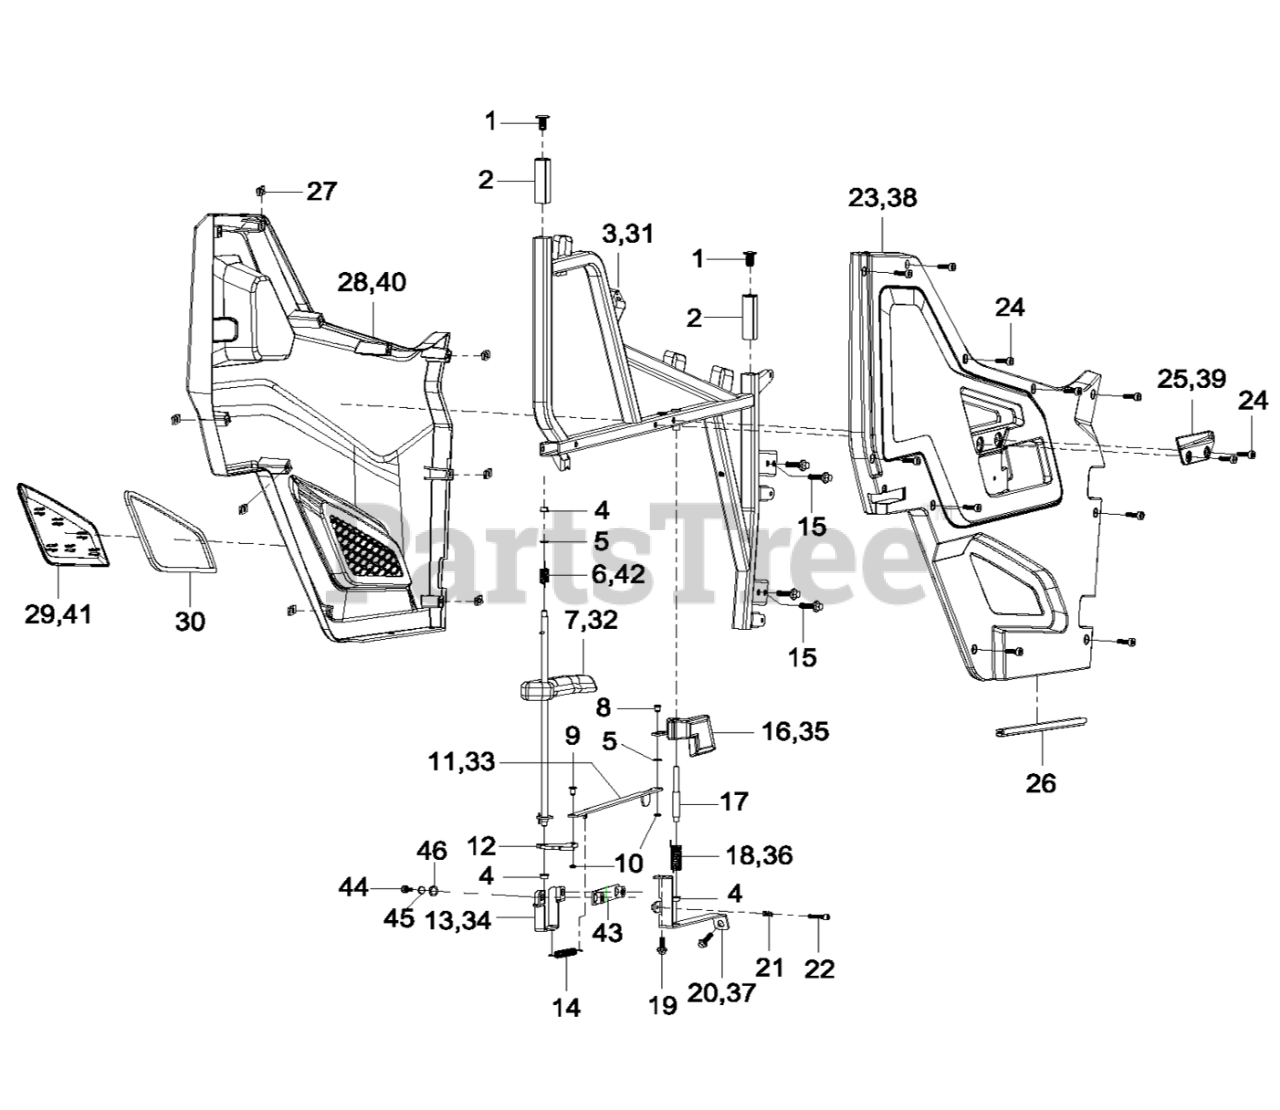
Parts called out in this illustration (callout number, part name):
1	PLUG - DOOR
2	UPPER DOOR SEAL
3	DOOR FRAME - LEFT LOWER
4	BUSHING PLASTIC 8X11
6	RETURN SPRING
7	OUTSIDE DOOR HANDLE KIT - LEFT
8	PIN - SHOULDER 8X11
9	PIN - SHOULDER 8X14
11	DOOR LOCK ROD - LEFT
12	DOOR LOCK KIT
13	INSIDE DOOR LOCK LEVER - LEFT
14	EXTENTION SPRING
15	HEXAGON FLANGE BOLT M8X20
16	INSIDE DOOR HANDLE KIT - LEFT
17	PIN - SHOULDER 8X104-12X47
18	SPRING - TORSION
19	HEXAGON FLANGE BOLT M6X16
20	INSIDE DOOR LOCK LEVER - LEFT
21	EXTENTION SPRING
22	HEX HEAD CAP SCREW M6X40
23	DOOR PROTECTOR - LEFT INSIDE I
24	SOCKET HEX FLAT HEAD BOLT M6X16
25	DOOR PULL - LEFT
27	CLAMP NUT M6X6
28	DOOR PROTECTOR - LEFT OUTSIDE I
29	DOOR BREATHER COVER - LEFT (RED)
29	COVER DOOR BREATHER (LH) (YELLOW)
29	COVER DOOR BREATHER LH BLUE
29	COVER DOOR BREATHER LH BLACK
29	COVER DOOR BREATHER RH CAMO
31	DOOR FRAME- RIGHT KIT
32	OUTSIDE DOOR HANDLE KIT - RIGHT
33	DOOR LOCK ROD - RIGHT
34	INSIDE DOOR LOCK LEVER - RIGHT
35	INSIDE DOOR HANDLE KIT - RIGHT
36	SPRING - TORSION
37	INSIDE DOOR LOCK - RIGHT
38	DOOR PROTECTOR - RIGHT INSIDE I
39	DOOR PULL - RIGHT
40	DOOR PROTECTOR - RIGHT OUTSIDE I
41	DOOR BREATHER COVER - RIGHT (RED)
41	COVER DOOR BREATHER (RH) (YELLOW)
41	COVER DOOR BREATHER RH BLUE
41	COVER DOOR BREATHER RH BLACK
41	COVER DOOR BREATHER LH CAMO
42	RETURN SPRING
43	SEAT MOUNTING PLATE LOCK
44	HEXAGON FLANGE BOLT M8X20
45	SPRING WASHER-8
